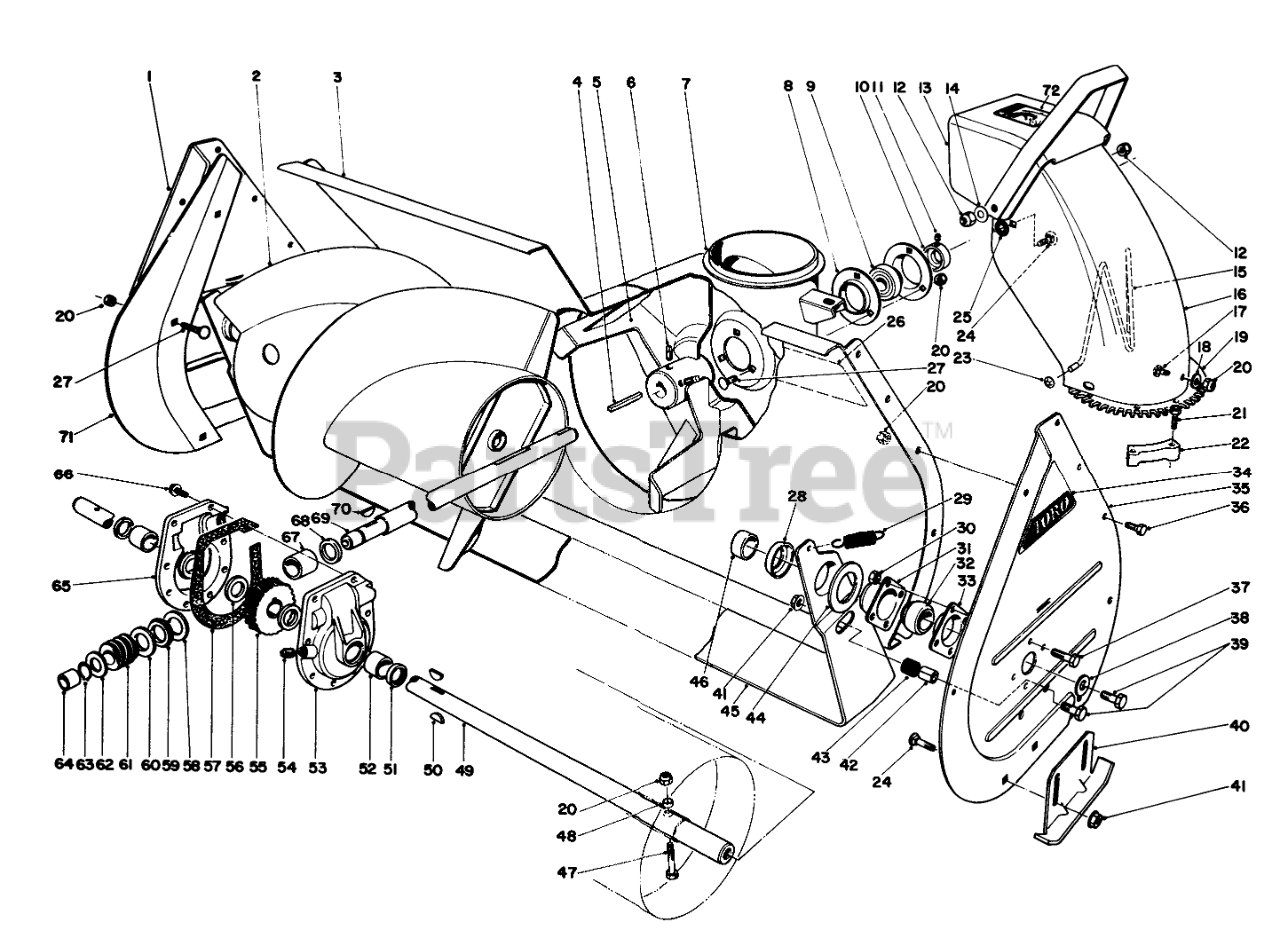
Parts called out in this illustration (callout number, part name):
1	RH AUGER SIDE PLT R
2	RH AUGER ASM - 32"
3	Auger Housing
5	IMPELLER ASM
6	SCREW-SET, SQH
7	CHUTE RING
8	BRG FLANGE
9	Bearing-Impeller (Incl. Ref.10 & 11)
10	EXT LOCKING COLLAR
11	SCREW-HSH
12	NUT-LOCK, CONE
13	Deflector
14	WASHER-BELLEVILLE
15	WIRE-CHUTE
16	Upper Chute
17	SCREW-CARR
18	WASHER-PLAIN
19	Screw
20	NUT-LOCK, NI
21	SCREW-SPECIAL
22	RETAINER-CHUTE
23	NUT-PUSH
24	SCREW-CARR
25	WASHER-RUBBER
26	Decal-Warning
27	BOLT-CARR
28	Positioner-Scraper
29	SPRING-TENSION
30	NUT-LOCK, CONE
31	BEARING-FLANGE, FRONT
32	BEARING
33	BEARING-FLANGE, REAR
34	AUGER SIDE PLT DECAL
35	LH AUGER SIDE PLT R
36	SCREW-HH
37	SCREW-HH
38	WASHER
39	SCREW-HH
40	AUGER SKID WA R
41	NUT-HF
42	SCRAPER STOP SPACER
43	SCRAPER STOP CUSHION
44	SCRAPER BLADE SPACER
45	SCRAPER BLADE 32" R
46	AUGER SPACER
47	Auger Bolt
48	SPACER-HUB, AUGER
49	32 AUGER SHAFT
50	KEY-WOODRUFF
51	SEAL-OIL
52	BUSHING
53	Gear Case Bushing Assy.-L.H. (Incl. Ref. #51, 52)
54	PLUG-PIPE, SQH
55	GEAR-WORM, 27T
56	WASHER-THRUST
57	GASKET-CASE, GEAR
58	WASHER-THRUST
59	BEARING-THRUST
60	THRUST-WASHER
62	WASHER-THRUST
63	Ring-Snap
64	BUSHING
65	Gear Case Bushing Assy.-R.H. (Incl. Ref. #51, 52)
66	SCREW-TAPTITE
67	BUSHING-SPECIAL
68	RING-QUAD
69	SHAFT-IMPELLER
70	KEY-WOODRUFF
71	Auger Housing Extension R.H.
72	Decal-Danger
